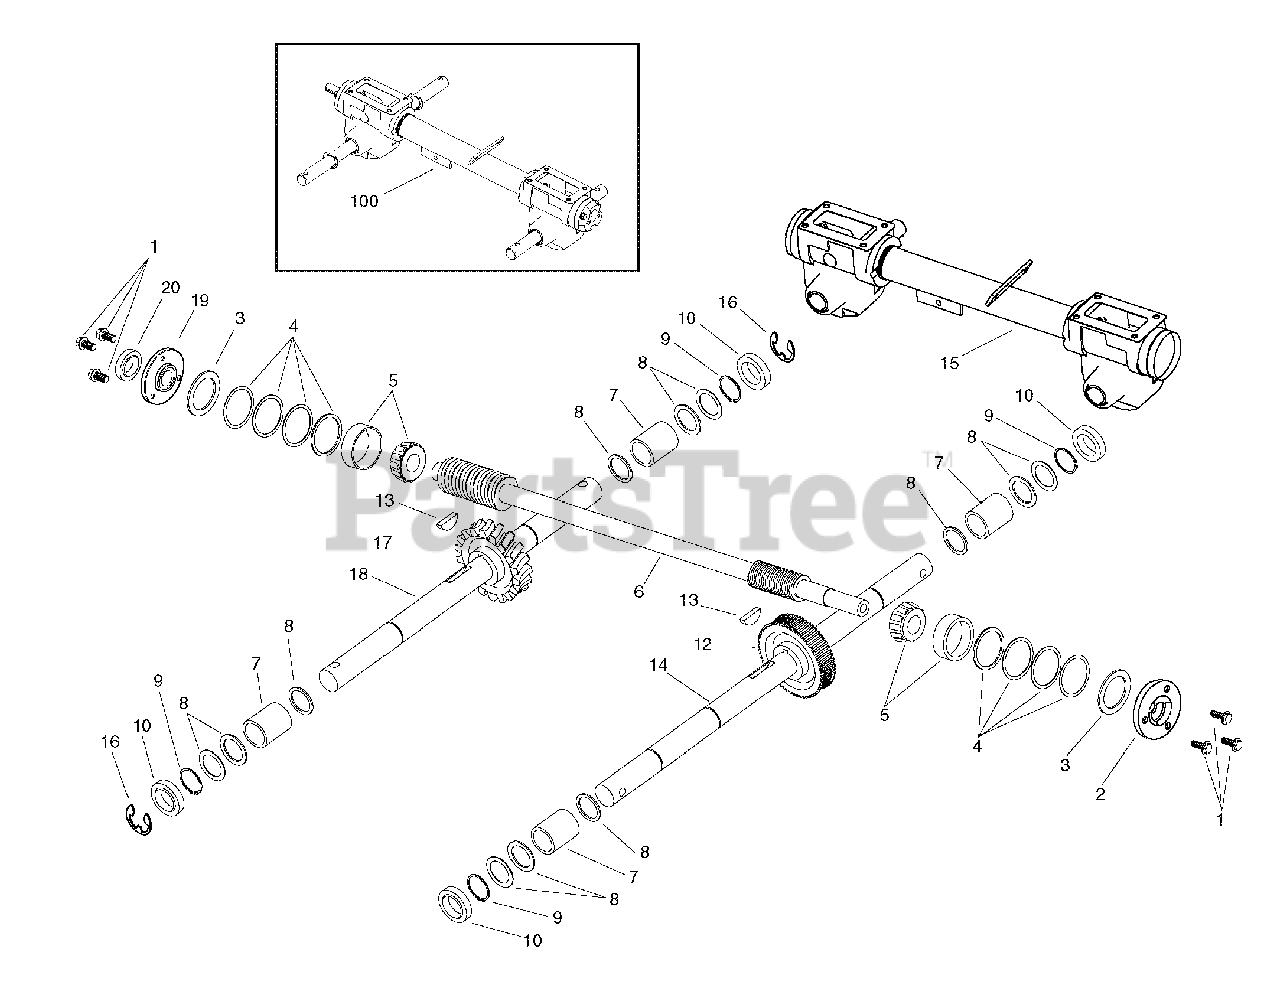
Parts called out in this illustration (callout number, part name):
1	BOLT, M6 x 25mm
2	** COVER, Rear Transmission
3	GASKET, Front & Rear tansmission Cover
4	* SHIM, Drive shaft
5	* BEARING, Tapered Roll
6	** SHAFT, Drive CRT
7	* BUSHING, TIne & Wheel Shaft
8	* SHIM, Tine & Wheel Shaft
9	RING, Retainer Shaft
10	SEAL, Grease Tine & Wheel
12	** GEAR, Worm Tine, CRT
14	* SHAFT, Tine
15	** HOUSING, Transmission
16	RING, Retainer, External
17	** GEAR, Worm Wheel, CRT
18	** SHAFT, Wheel
19	** COVER, Front Transmission
20	SEAL, Grease Input
100	TRANSMISSION ASSEMBLY CRT6
